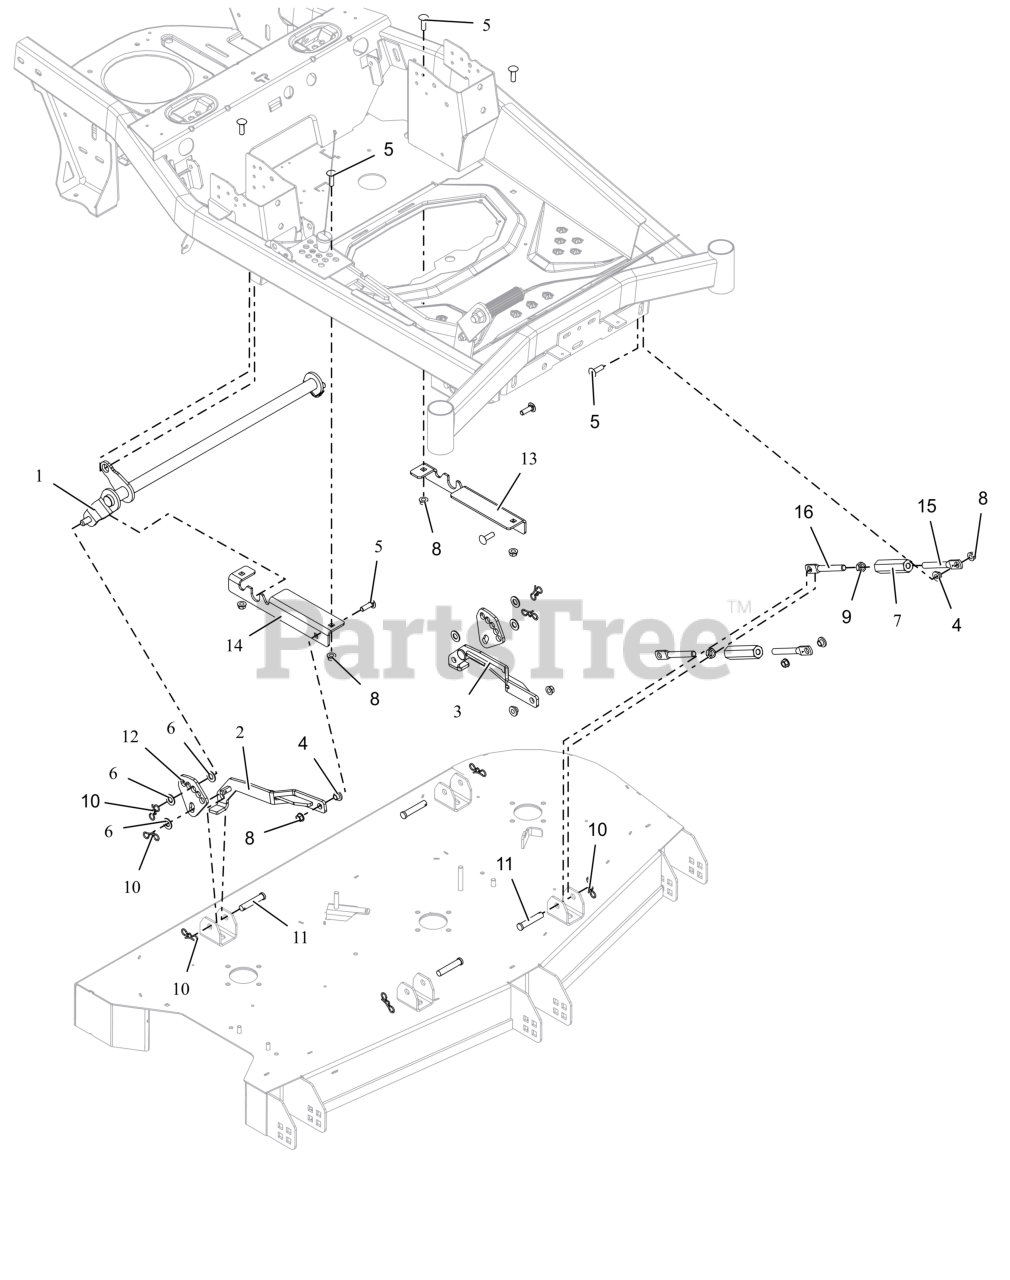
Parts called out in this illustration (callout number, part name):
1	WLDMT- DECK LIFT SHAFT
2	WLDMT, REAR DECKLIFT BRKT-RH (ORANGE)
3	WLDMT, REAR DECKLIFT BRKT-LH (ORANGE)
4	BSHG-FLG .385X.500X.875X.406
5	BLT,RHSSN .38-16X1.25 G5 ZCC
6	WSHR-FL-NYL .518X1.000X.080
7	NUT-COUPLER .500 LH/RH
8	NUT-LK-CTR-FLG .375-16 GF ZCC
9	NUT-JAM .500-13 G2 ZCC
10	PIN, BOWTIE .091X1.875 ZCC
11	PIN-CLEV .494X2.50 BRIGHT ZINC
12	BRKT- DECK HEIGHT ADJUSTER-ORG
13	PLATE, DECK LIFT MTG-LH (ORANGE)
14	BRKT, LIFT MOUNTING (ORANGE)
15	ROD- FRONT LIFT-LH
16	LINK- DECK -RH
